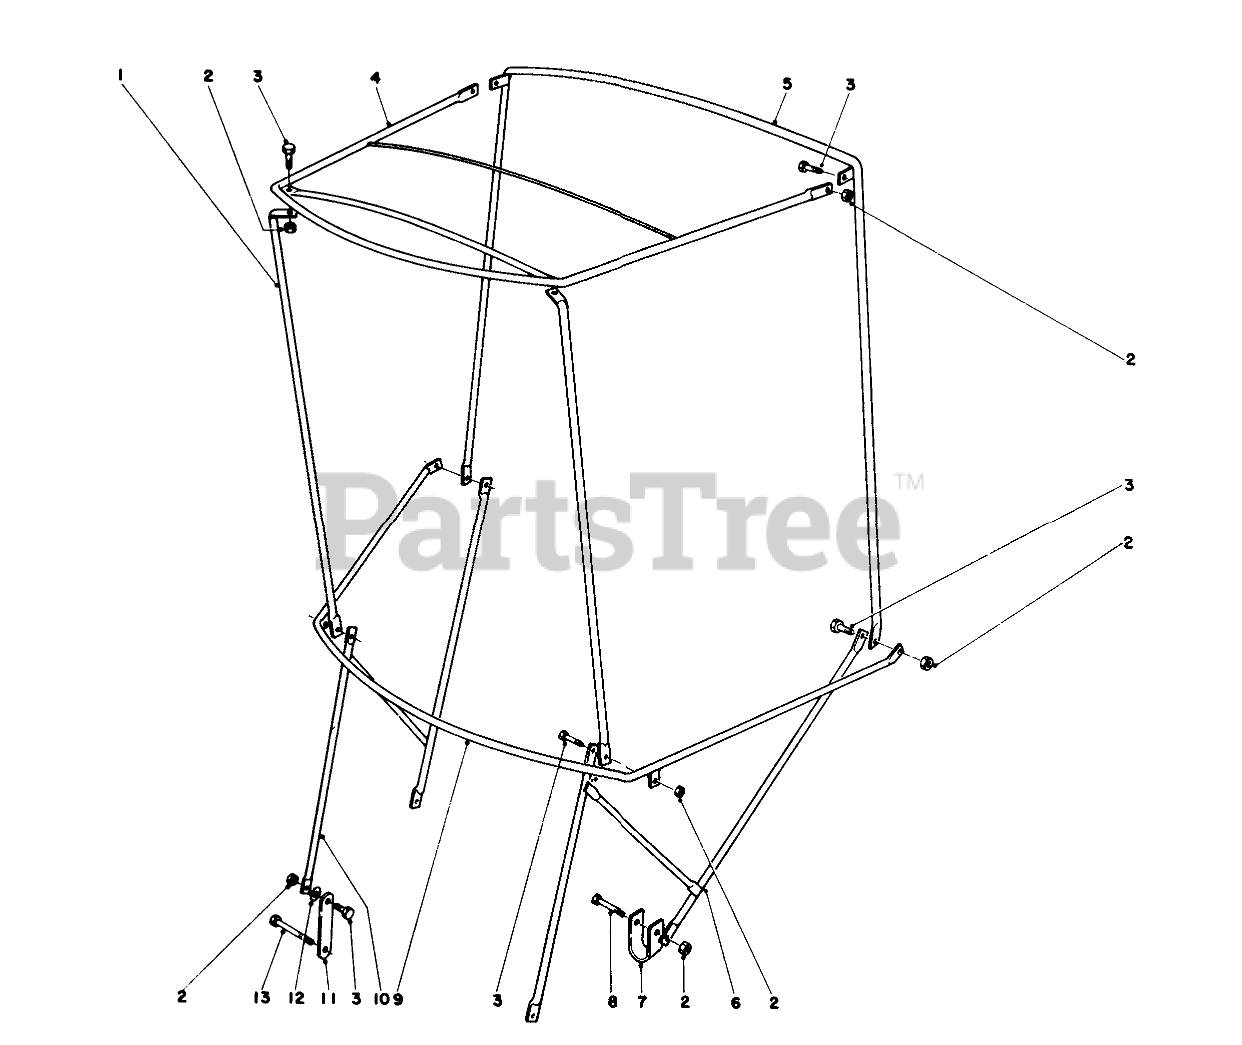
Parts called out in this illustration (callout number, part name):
2	NUT-LOCK
3	SCREW-HH
4	FRAME-TOP
5	BOW-VERTICAL, REAR
6	Attaching Bracket, L.H.
7	U CLAMP
8	SCREW-HH
9	BOW-CURVED
10	Attaching Bracket, R.H.
11	Mounting Strap
12	WASHER-LOCK/EXT
13	SCREW-HH
